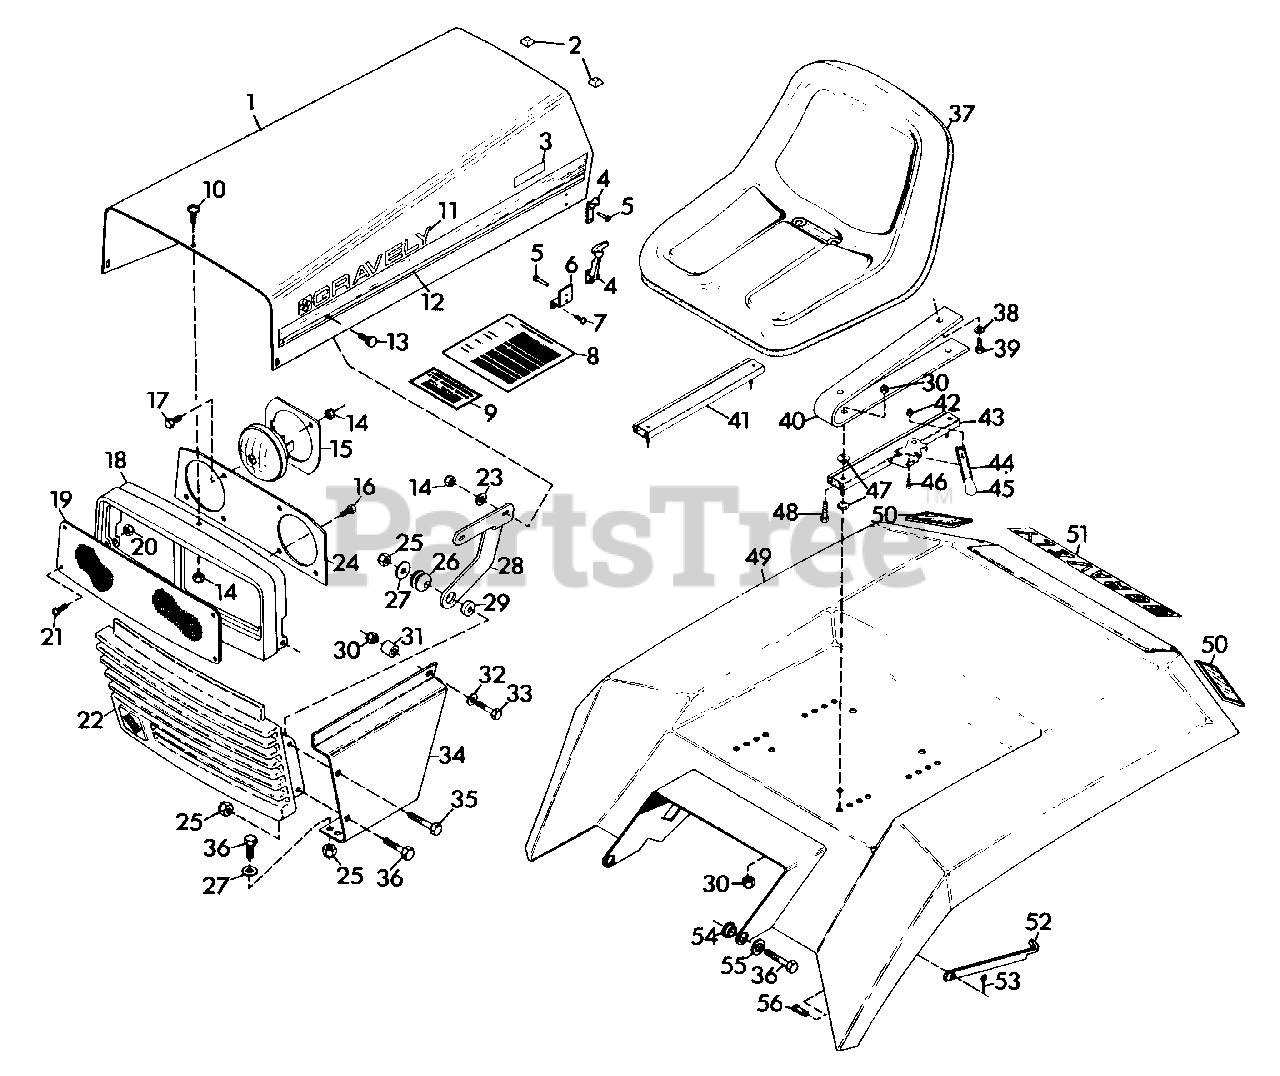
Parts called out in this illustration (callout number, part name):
1	HOOD, SILK SCREEN
2	STOP
3	DECAL, MODEL 12-G
3	DECAL, MODEL 16-G
3	DECAL, MODEL 18-G
3	DECAL, MODEL 20-G
4	LATCH, FLEXIBLE
5	RIVET, DOME HEAD
6	BRACKET, HOOD LATCH MOUNTING
7	SCREW, 8-18X.375 PHD CR
8	DECAL, MAINTENANCE
9	DECAL, ELECTRICAL SYSTEM WARNING
10	SCREW, MACHINE 1/4-20 PHD
11	DECAL, GRAVELY LOGO
12	DECAL, SIDE STRIPE L.H. AND R.H.
13	BOLT, 1/4-20X.75 RD HD SQ NK
14	NUT, LOCK 1/4-20
15	RING, HEADLIGHT RETAINER
16	SCREW, 1/4-20X.50 SELF-TAPPING
17	BOLT, HEX 1/4-20X1.00
18	BEZEL, HEADLIGHT
19	PANEL, HEADLIGHT LENSE
20	NUT, LOCK 10-24
21	SCREW, MACHINE 10-24X.75 PHD
22	CASTING, GRILLE
23	WASHER, FLAT .281X.625X.065
24	PANEL, HEADLIGHT REFLECTOR
25	NUT, LOCK 3/8-16
26	GROMMET
27	WASHER, FLAT .438X1.000X.083
28	HINGE, HOOD L.H.
28	HINGE, HOOD R.H.
29	SPACER
30	NUT, LOCK 5/16-18
31	SPACER, .375X.100X1.00
32	WASHER, FLAT .344X.688X.065
33	BOLT, HEX 5/16-18X1.75
34	PANEL, SIDE L.H.
34	PANEL, SIDE R.H.
35	BOLT, HEX 3/8-16X2.00
36	BOLT, HEX 3/8-16X1.00
37	SEAT, HIGH BACK
38	WASHER, LOCK 5/16 REG.
39	BOLT, HEX 5/16-18X.75
40	SPRING, SEAT
41	ADJUSTER, SEAT
42	NUT, LOCK 10-24
43	ADJUSTER, SEAT W/LATCH
44	HANDLE, SEAT SLIDE
45	TIP, LEVER
46	SCREW, MACHINE 10-24X.625 PHD
47	SPACER
48	BOLT, HEX 5/16-18X1.25
49	WELDMENT, SEAT PAN
49	WELDMENT, SEAT PAN NOTCHED
50	REFLECTOR, RED SAFETY
51	DECAL, GRAVELY LOGO
52	STRAP, FENDER HOLD-UP
53	PIN, COTTER .06X.75
54	BUSHING, REAR FENDER
55	WASHER, FLAT .406X.812X.065
56	PIN, CLEVIS .250X.406
